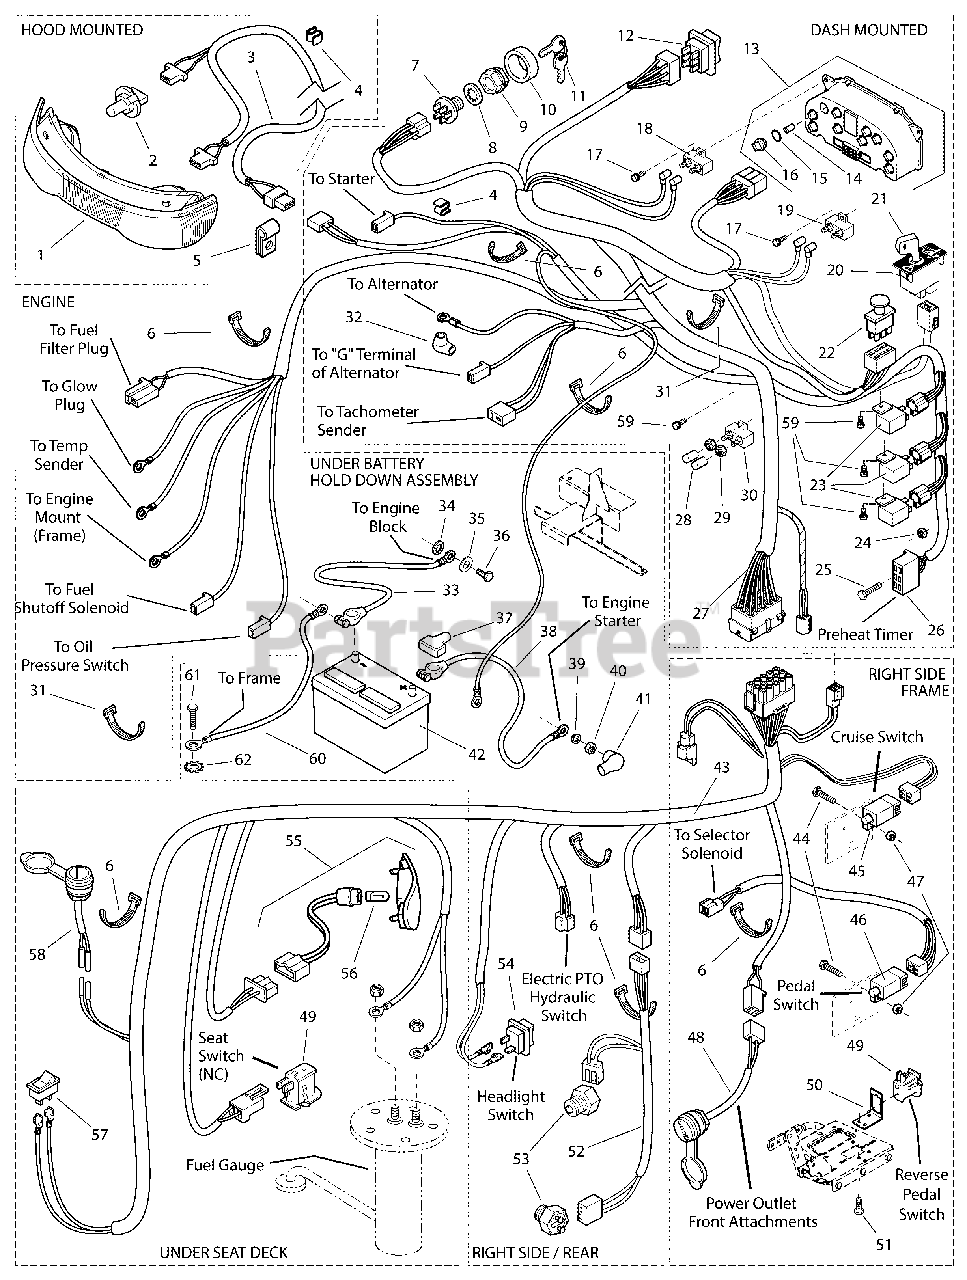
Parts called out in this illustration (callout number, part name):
2	BULB, Headlight, Halogen
3	HARNESS, Headlight
5	CLAMP, Wire 3/8 Diameter
6	TIE, Self Locking 7 in. Long
7	SWITCH ASSEMBLY, Ignition 5/8-32, 6 Pin INDAK
8	LOCKWASHER, Internal Tooth, 5/8, Thin
9	NUT, Hex Flange 5/8-32 Ignition Switch
10	COVER, Ignition Switch, Black
11	KEYS, Set of 2
12	SWITCH, Electric Lift, 6 Terminal
13	PANEL, Instrument
14	BULB, Instrument Panel
15	SEAL, Lamp Socket Plug
16	HOLDER, Bulb, Instrument Panel (Includes Ref. No. 15)
17	SCREW, Hex Washer Head, Thread Cutting, #12-24 x 5/8
18	BREAKER, Circuit 12VOLT 10AMP
19	BREAKER, Circuit 12VOLT 20AMP with Tab
20	SWITCH, RMO Module Only
21	KEY, RMO Module, Plastic
22	SWITCH, PTO Push/Pull, Yellow
23	RELAY, 12VOLT 5 Blade
24	NUT, Hex Lock 10-24 with Nylock Insert, NC3B
25	SCREW, Round Head Phillips #10-24 x 3/4
26	RELAY, Glow Plug
27	HARNESS, Main Diesel
28	COVER, Wire, Black, Vynil
29	NUT, Hex & Washer Assembly, KEPS
30	BREAKER, Circuit 30AMP 12VOLT
31	TIE, Self Locking 15 in. Long
32	COVER, Terminal Red
33	CABLE, Battery, # 4 x 10 in Long, Black
34	LOCKWASHER, External Tooth 5/16
35	WASHER, 3/8
36	CAPSCREW, Hex Head M08-1.25 x 16MM
37	INSULATOR, Battery Terminal, Red
38	CABLE, Battery, # 4 x 15 in Long, Red
39	LOCKWASHER, Spring 5/16
40	NUT, Hex Flange M08-1.25
41	BOOT, Cable Terminal
42	BATTERY, 12VOLT 6CELL 500AMPS CCA
43	HARNESS, Rear
44	SCREW, Hew Washer Head Slot, #10-24 x 5/8
45	SWITCH, Push Button, Cuise Control
46	SWITCH, Push Button, Foot Pedal
47	NUT, Hex KEPS #10-24
48	HARNESS ASSEMBLY, Power Outlet
49	SWITCH-PUSH BUTTON (NO) REGENT
50	BRACKET, Switch Mounting, Reverse Pedal
51	CAPSCREW, Hex Head Taptite, 1/4-20 x 3/8
52	HARNESS, Trasnmission, PTO Lights (540 PTO Only)
53	SWITCH, Interlock Ball Check 5/16 (540 PTO Only)
54	SWITCH, Headlights, 2 Terminal
55	TAIL LIGHT ASSEMBLY
56	BULB, Tail Light
57	SWITCH, Rocker, Solenoid Select
58	OUTLET, 12 Volt
59	FASTENER, Panel
60	CABLE-# 6 X 15.0 LG (2) RING TERMINALS BLACK
61	SCREW-HEX WASHER HD TAPTT 3/8-16 X 1
62	LOCKWASHER-EXTERNAL TOOTH .375 YELLOW
